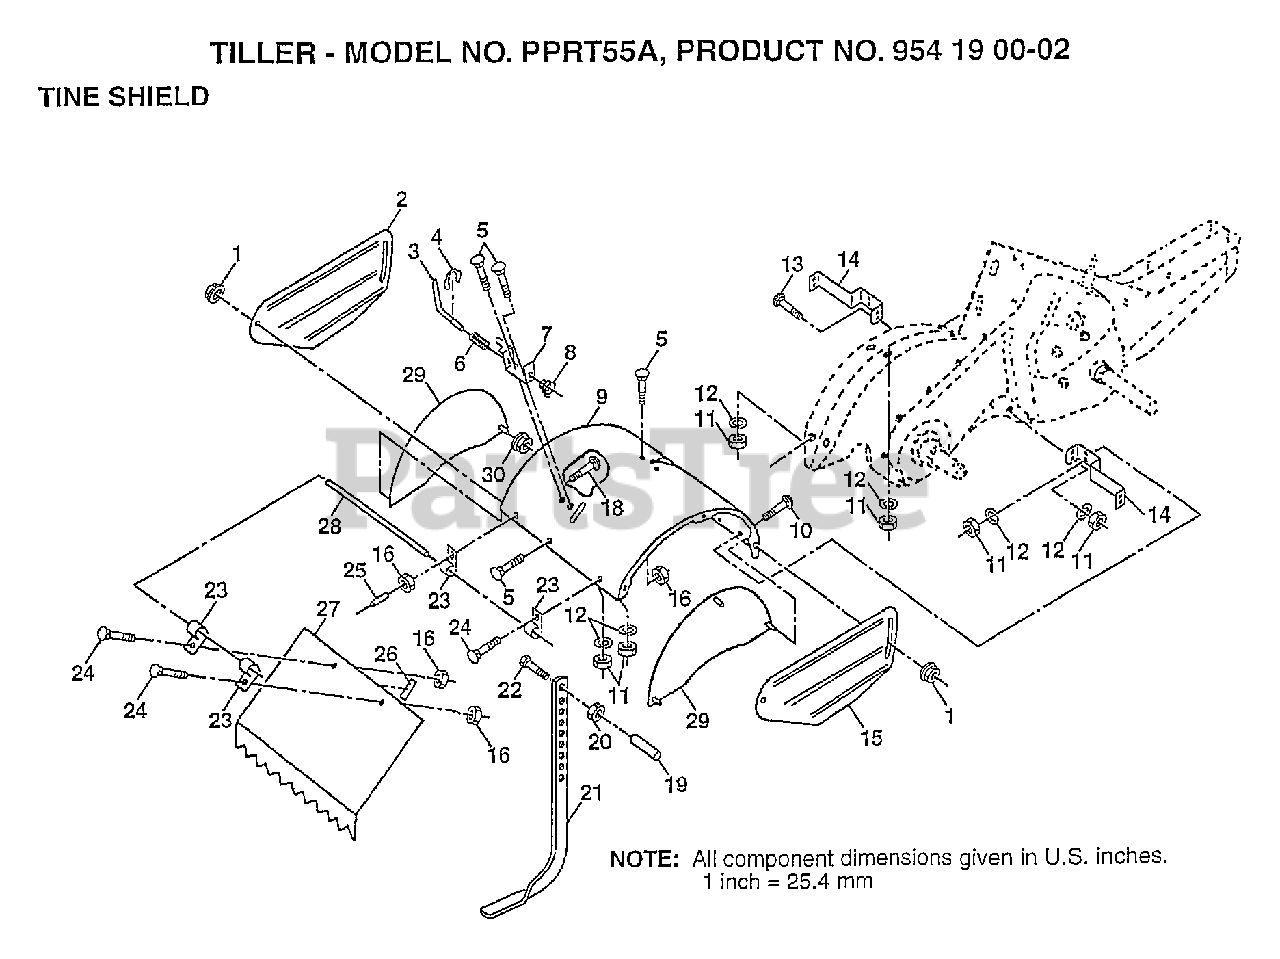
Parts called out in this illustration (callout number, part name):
1	NUT
2	SHIELD SIDE OUTER
3	STAKE PIN TI
4	KLIP RING TI
5	BOLT
6	SPRING TI
7	LATCH BRACKET TI
8	SPRING DEPTH STAKE
9	SHIELD TINE
10	BOLT
11	NUT.HEX.5/16-18
12	LOCKWASHER
13	BOLT
14	"BRACKET,SHIELD"
15	SHIELD SIDE OUTER
16	NUT
18	BOLT
20	NUT.HEX.3/8-16UNC
21	STAKE DEPTH
22	BOLT
23	HINGE CRT
24	BOLT
27	SHIELD LEVELING
29	SHIELD SIDE
30	LOCKNUT TI
